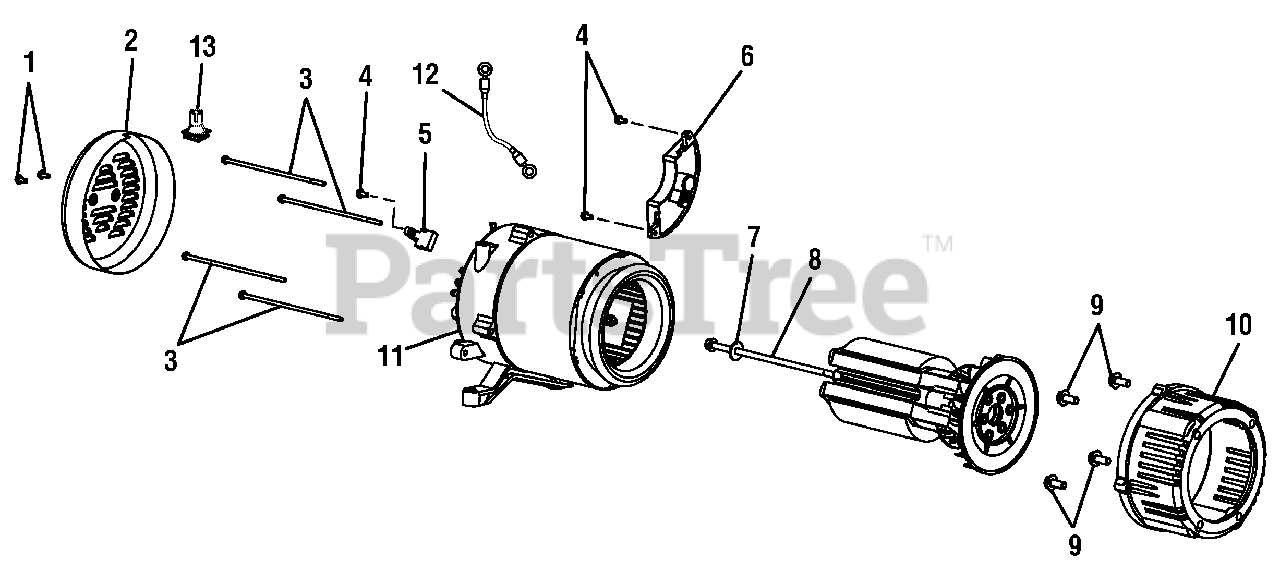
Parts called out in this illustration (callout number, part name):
1	BOLT (M5 X 10 MM FLANGEHEX HD)
2	BRUSH COVER
3	BOLT (1/4-20 X 6 IN. HEX HD.)
4	BOLT (M5 X 16MM FLANGE HEX HD)
5	BRUSH ASSEMBLY
6	AUTOMATIC VOLTAGE REGULATOR
7	WASHER (5/16 IN.)
8	BOLT (5/16-24 X 230 MM HEX HD)
9	BOLT (3/8-16 X 1-1/4 IN.)
10	ENGINE ADAPTER
11	BEARING SUPPORT
12	BONDING WIRE
13	RUBBER BOOT
